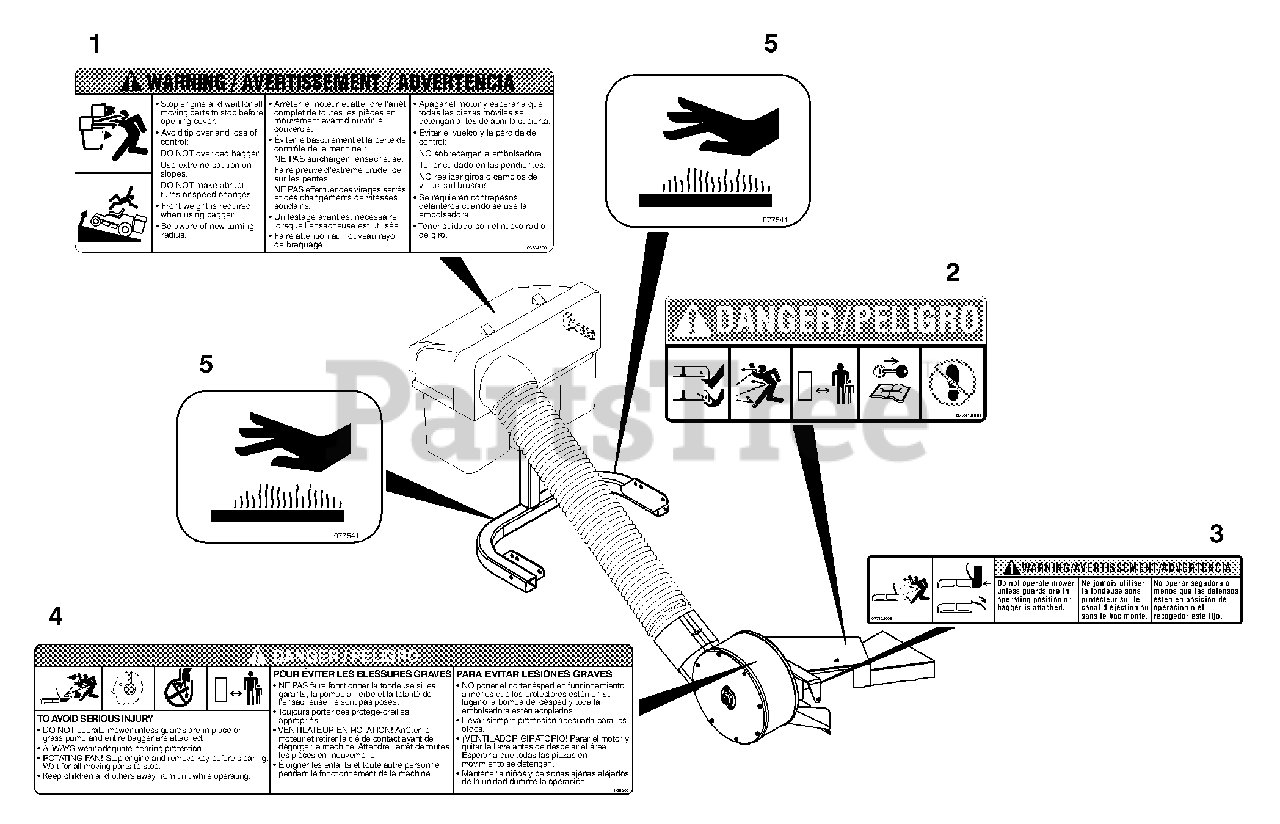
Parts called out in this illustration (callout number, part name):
1	Decal-Warning, Bagger Cover
2	Decal, Mower Pan Head Danger
3	Decal, Warning
4	Decal-Caution, Grass Pump
5	Decal, Hot Surface
